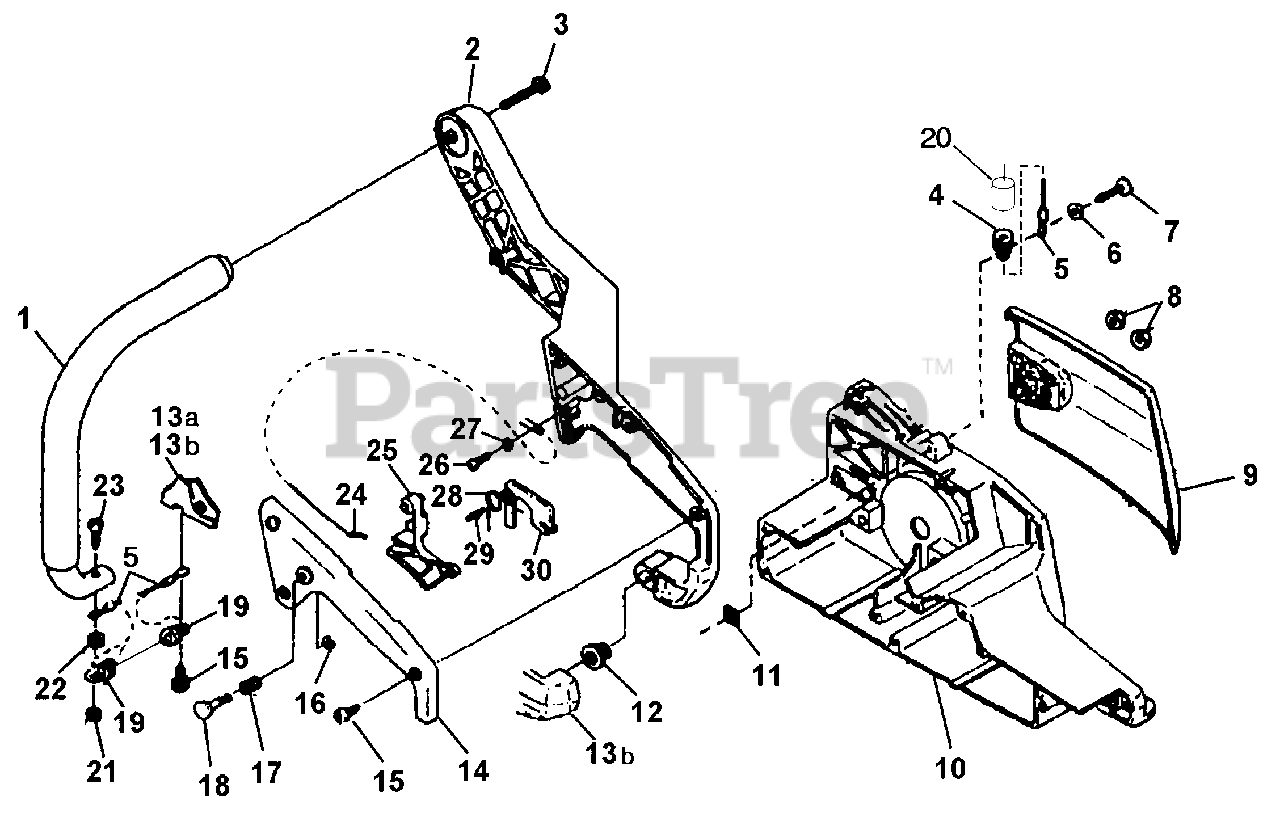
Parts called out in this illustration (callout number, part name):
1	HANDLE BAR
2	REAR HANDLE
3	SCREW, HEX Hd (12-24 X 7/8")
4	SPRING, EXTENSION
5	RETAINER, SPRING
6	WASHER,FLAT (#12)
7	SCREW, PAN Hd. (10-24 X 7/8")
8	NUT, HEX
9	COVER, DRIVE CASE
10	ENG. HSG. DRIVE SIDE
11	NUT, SQUARE (# 10-24)
12	ISOLATOR, VIBRATION
13A	HSG., STARTER SIDE
13B	HSG., STARTER SIDE
14	COVER, REAR HANDLE
15	SCREW, THREAD FORM (8-16 X 5/8")
16	RING, RETAINING
17	SPRING, COMPRESSION
18	PIN, THROTTLE LOCK
19	SPRING, EXTENSION
20	SLEEVE, SPRING
21	NUT, HEX
22	WASHER, FLAT (#12)
23	SCREW, TORX (10-24 X 1/2")
24	CABLE, THROTTLE
25	TRIGGER, THROTTLE
26	SCREW, THREAD FORM (6-19 X 1/2")
27	WASHER, FLAT
28	SPRING, THROTTLE
29	PIN, DOWEL
30	LOCK, THROTTLE
